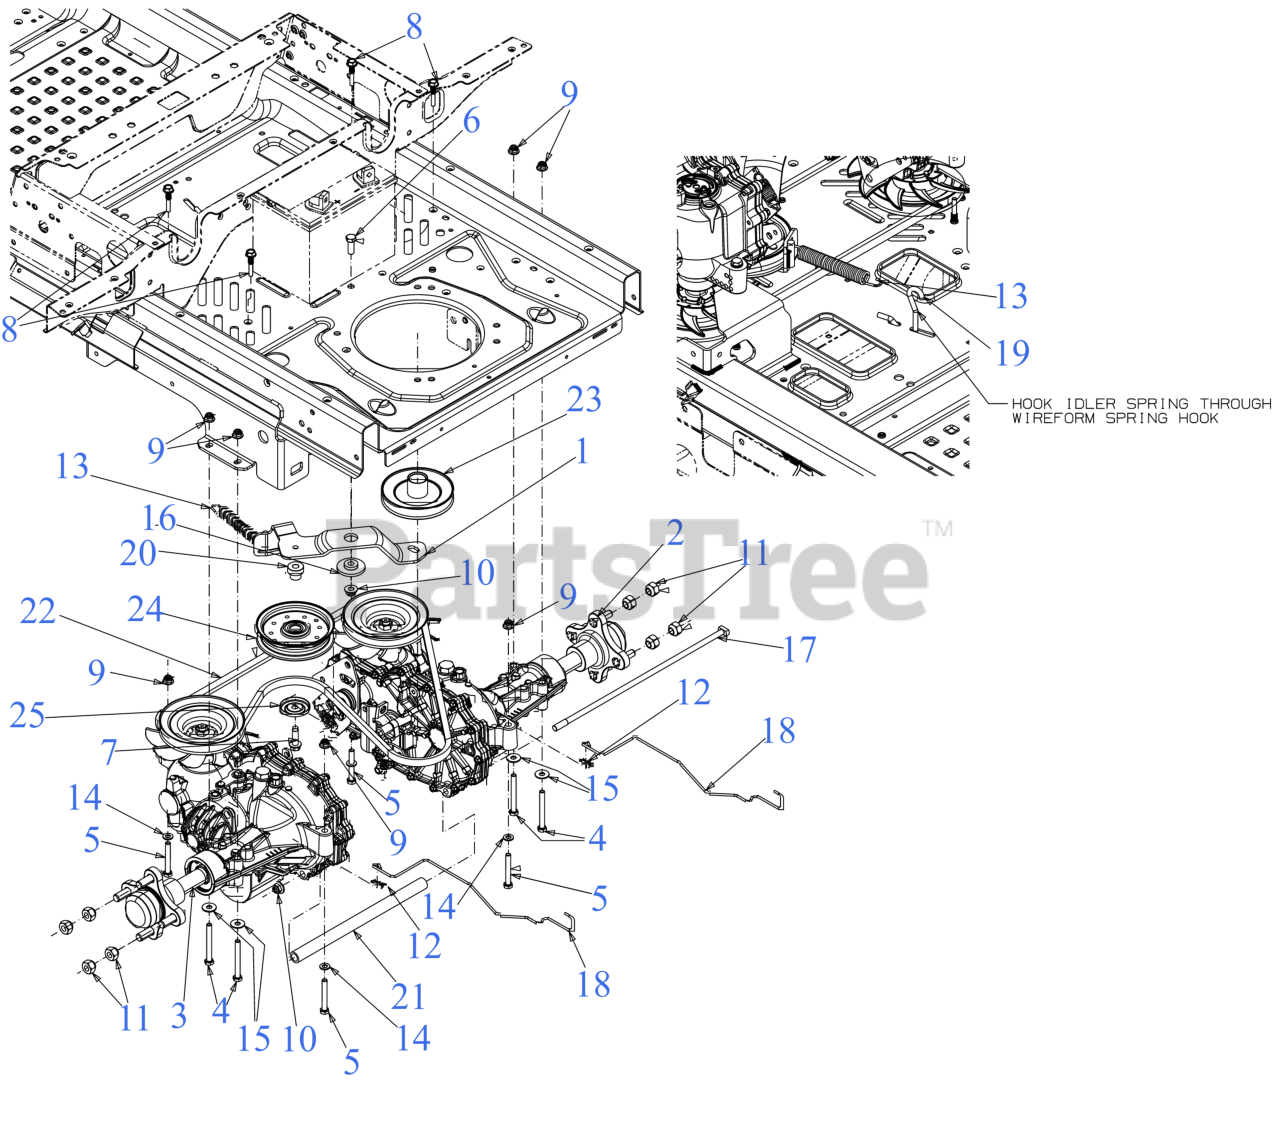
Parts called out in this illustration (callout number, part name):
1	IDLER BRACKET ASSEMBLY
2	TRANSMISSION (RH)
3	TRANSMISSION (LH)
4	HEX SCREW 5/16-18 x 2.75
5	HEX SCREW 5/16-18 x 2.25 GR5
6	SCREW 3/8-16 x 1 GR5
7	SCREW 3/8-16 X1.250
8	BELT KEEPER ROD .25 x 1.585
9	FLANGE LOCK NUT 5/16-18
11	LUG NUT 7/16-14
12	BOW TIE COTTER PIN 1/4-5/16
13	EXTENSION SPRING .75 DIA x 5.87
14	FLAT WASHER
15	FLAT WASHER
16	SHOULDER SPACER
17	SUPPORT TUBE ROD
18	HYDRO BYPASS ROD
19	IDLER SPRING HOOK
20	SHOULDER SPACER
21	TRANSMISSION SPACER .75OD x 11.31
22	TRANSMISSION DRIVE BELT A x 67
22	Cub Cadet TRANS DRIVE BELT A x 67 RZT
22	Troy-Bilt TRANSMISSION DRIVE BELT
23	TRANSMISSION DRIVE PULLEY
24	IDLER PULLEY 4.25 DIA
25	IDLER PULLEY CAP
